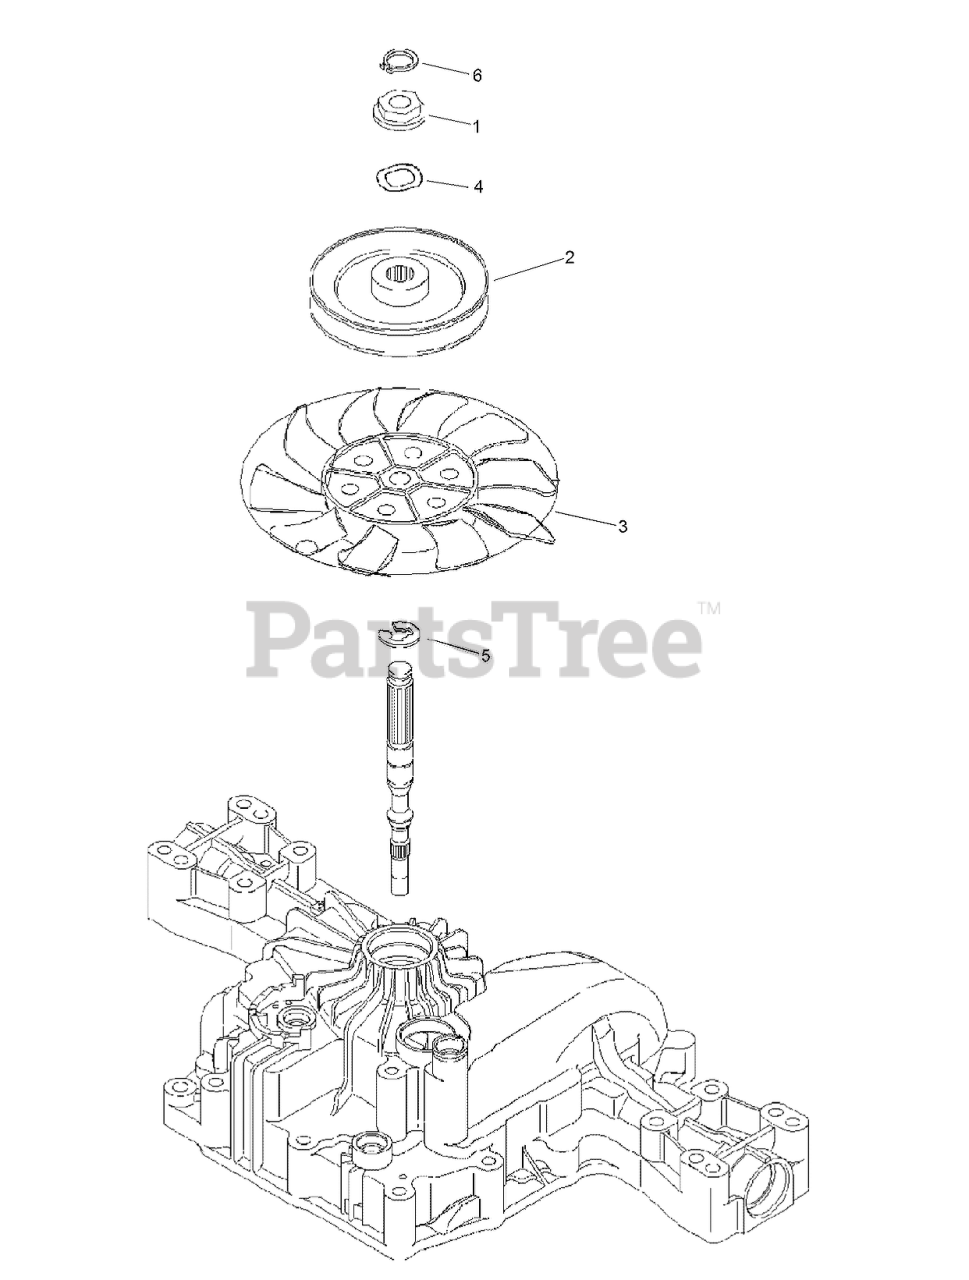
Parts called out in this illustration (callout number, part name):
1	Collar-Spline
2	PULLEY-TRANSMISSION
3	FAN-TRANSMISSION
4	Washer-Lock
5	E-RING
6	E-RING
